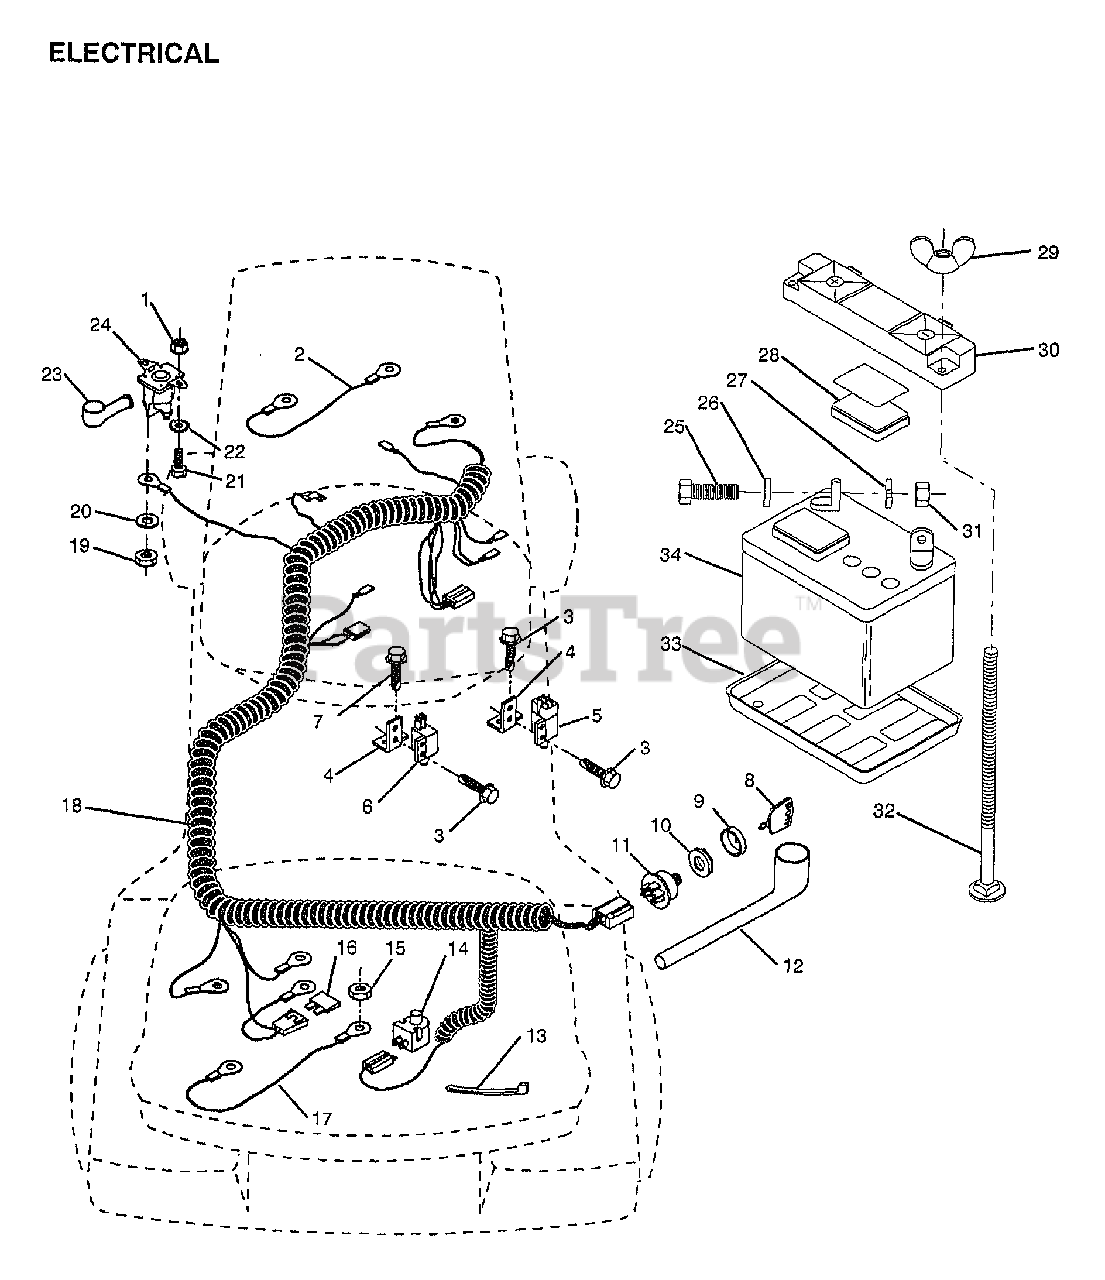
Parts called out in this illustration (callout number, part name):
1	NUT
2	CABLE LTV
3	SCREW
4	BRACKET LT
5	SWITCH INTERLOCKT
6	SWITCH-INTER. GT
7	SCREW
8	KEY
10	NUT IGNITION
12	COVER IGNITION SW
13	WIRE TIE
14	SWITCH SEAT
16	FUSE HYT
18	HARNESS IGNITION
19	NUT
21	BOLT
25	BOLT LT
26	WASHER
27	LOCKWASHER
28	"CAP,BATTERY "
32	BOLT
33	"TRAY T, BATTERY"
